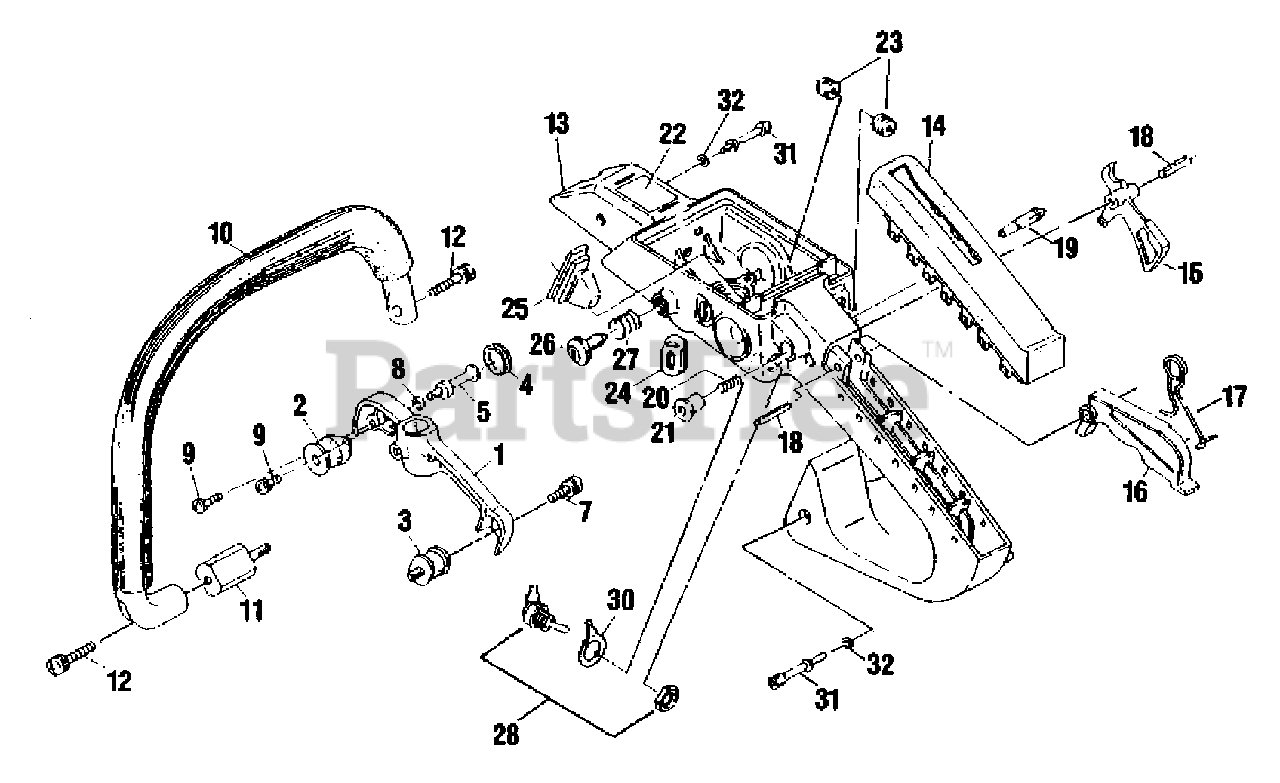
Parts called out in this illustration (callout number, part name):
2	CUSHION - 22
3	CUSHION - 18A
4	PLUG, BRACKET
5	BOLT, BRACKET
7	SCREW - 5X12
8	LOCKWASHER - 5
9	SCREW - 4X10
10	HANDLE - FRONT
11	CUSHION 22B, USE 72362-32310
12	SCREW - 5X25
13	HANDLE - REAR
14	GRIP, HANDLE
15	TRIGGER, THROTTLE
16	LEVER, LOCK
17	SPRING, LEVER
18	PIN - SPRING
19	PIN - LOCKING
21	KNOB, STOPPER
22	LABEL - CAUTION
26	SCREW, ADJUST
27	SPRING, ADJUST
28	SWITCH ASSY
30	PLATE - GROUND
31	BOLT
32	LOCKWASHER - 5
